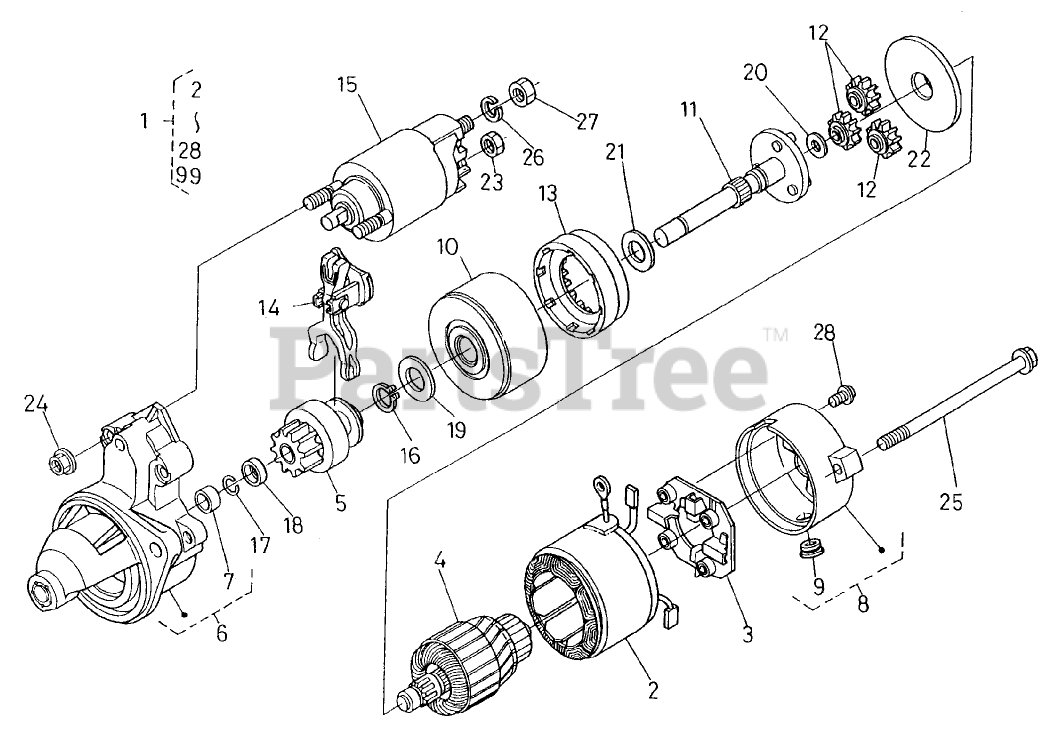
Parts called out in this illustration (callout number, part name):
1	STARTER ASM
2	STARTER YOKE ASM
3	HOLDER ASM
4	ARMATURE ASM
5	STARTER CLUTCH ASM
6	STARTER HOUSING ASM
7	BEARING
8	FRAME ASM
10	BEARING ASM
11	STARTER SHAFT ASM
15	MAGNETIC SWITCH ASM
16	RING-SNAP
17	RING-SNAP
18	COLLAR
19	WASHER-PLAIN
20	WASHER-PLAIN
21	WASHER-PLAIN
23	NUT-HEX
25	BOLT-THROUGH
26	WASHER-SPRING
27	NUT-HEX
99	WIRE-LEAD
